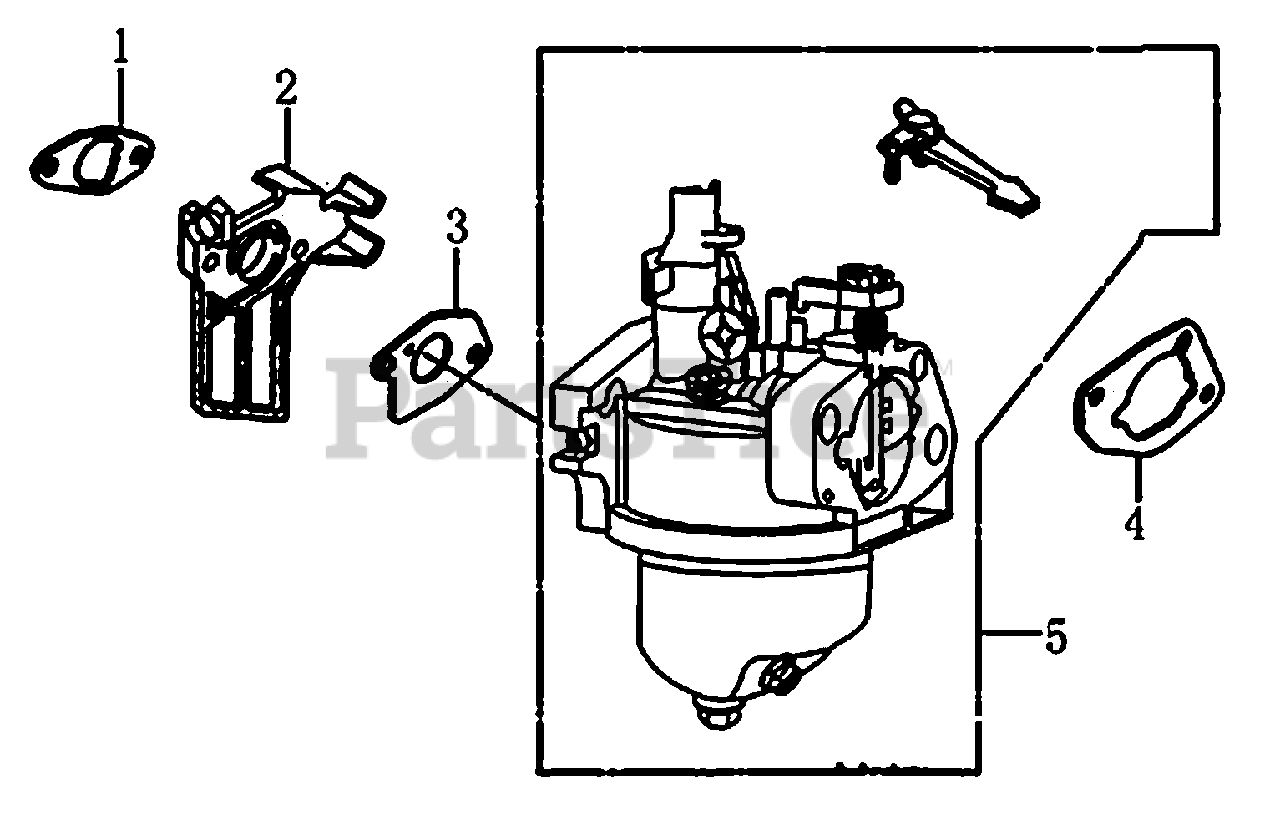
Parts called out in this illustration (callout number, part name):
1	GASKET, CARBURETOR
2	INSULATOR,CARBURETOR
3	GASKET, INSULATOR
4	GASKET, AIR CLEANER
5	CARBURETOR
